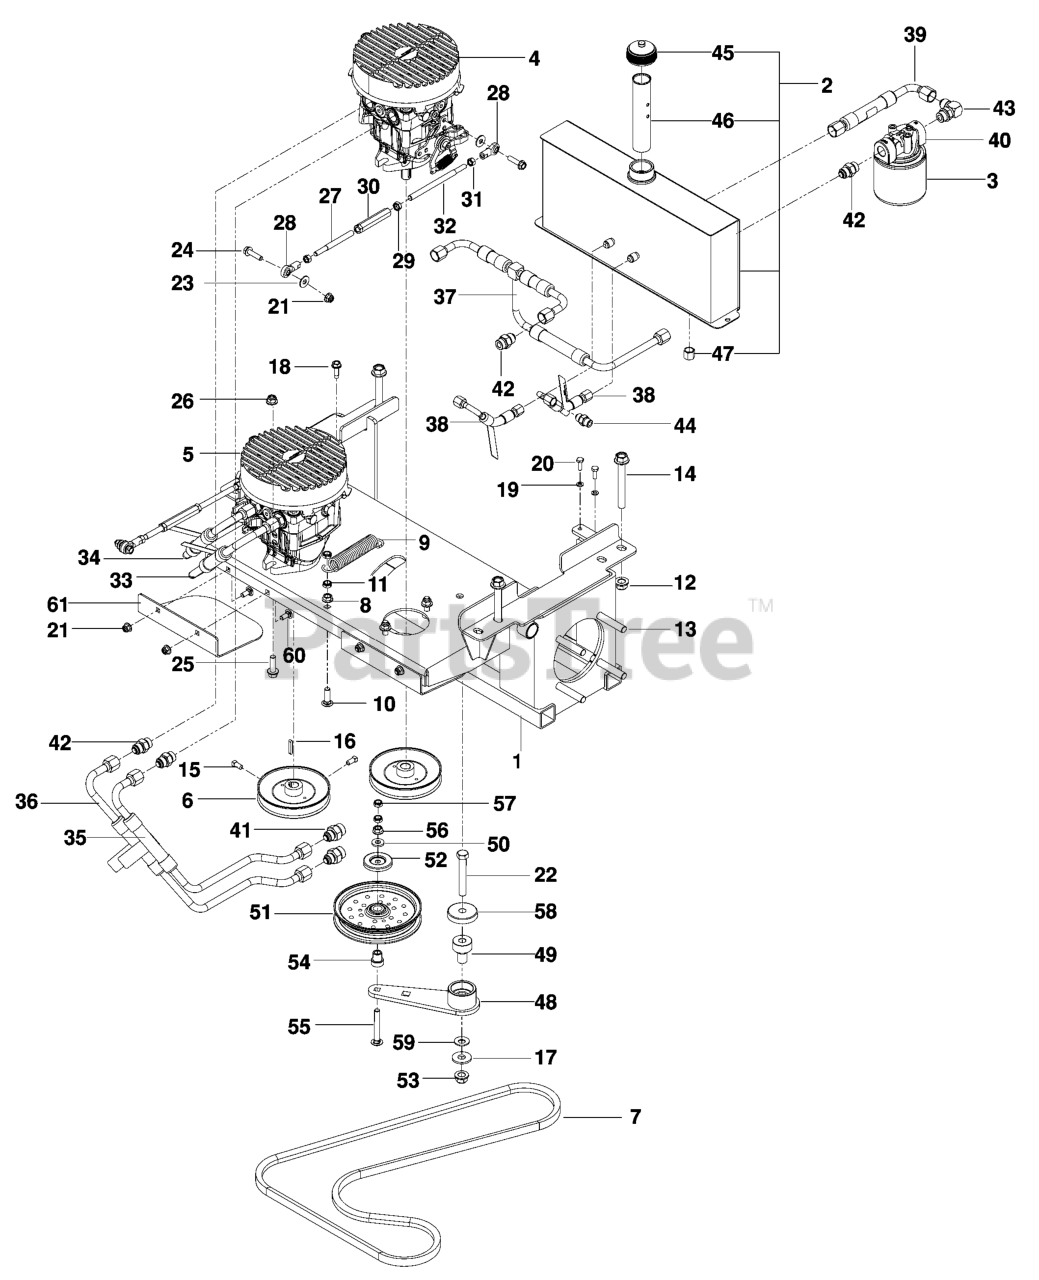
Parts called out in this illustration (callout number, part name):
1	FRAME, NYDR SUB, BLK
2	ASSEMBLY, OIL TANK
3	FILTER 25 MICRON
4	HG_PUMP, 16CC
5	HG_PUMP, 16CC
6	PULLEY, PUMP 17MM
7	BELT, "B", 75.5"
8	NUT 3/8C WHIZ
9	SPRING, PUMP
10	RHSNB 3/8-16 X 1-1/4
11	NUT HEX 3/8-16 NYLON, THIN
12	NUT, 1/2-13 HEX FLG NYLOC ZD
13	HCS 1/2C X 2 3/4
14	HHFS 1/2-13 X 4.0 GD8 ZD
15	SCREW 5/16C X 5/8 SQ HEAD
16	KEY 5 MM SQ X 25 MM
17	WASH USS FLAT 1/2
18	RP BLT 5/16-18 X 1 THRD FORM D
19	LOCKWASHER 1/4"
20	HCS 1/4C X 3/4 HCS
21	5/16-18 NYLOC FLANGE NUT
22	HCS 1/2C X 3 1/4
23	WASHER 5/16 FLAT
24	HHFS 5/16-18 X 1.25 TPBLT GD 5
25	HHFS 3/8-16 X 1.25 GD 5
26	NUT 3/8-16 HEX FLG NYLOC ZD
27	LINKAGE, CONTROL, FT
28	BALL JOINT, RIGHT HANDED
29	NUT 3/8-24 JAM
30	TURNBUCKLE, 3/8
32	LINKAGE, CONTROL, RR
33	LINE, RT A
34	LINE, RT B
35	LINE, LT A
36	LINE, LT B
37	LINE, CHARGE
38	LINE, CASE
39	LINE, SUCTION
40	FILTER HEAD
41	CONNECTOR, STRAIGHT
42	FITTING, STRAIGHT F6400-8-8-0
43	ELBOW, 90 DEGREE
44	STRAIGHT FITG
45	CAP, HYDRAULIC
46	TUBE, ANTI-SPLASH
47	NUT 9/16-18 JIC CAP
48	ARM, IDLER, STEEL, W/BGS
49	PIVOT, BEARING
50	WASHER, 3/8 THICK
51	IDLER, FLAT, 5.5"
52	DUST SHIELD
53	NUT, 1/2-13 HEX FLG NYLOC ZD
54	PIVOT, IDLER
55	RHSNB 3/8-16 X 2.75
56	NUT 3/8C WHIZ
57	NUT HEX 3/8-16 NYLON, THIN
58	SHIELD, DUST
59	CONTACT BELLSPR 1/2
60	BOLT 5/16C X 3/4" CARRIAGE
61	SHIELD, PULLEY, BLK
